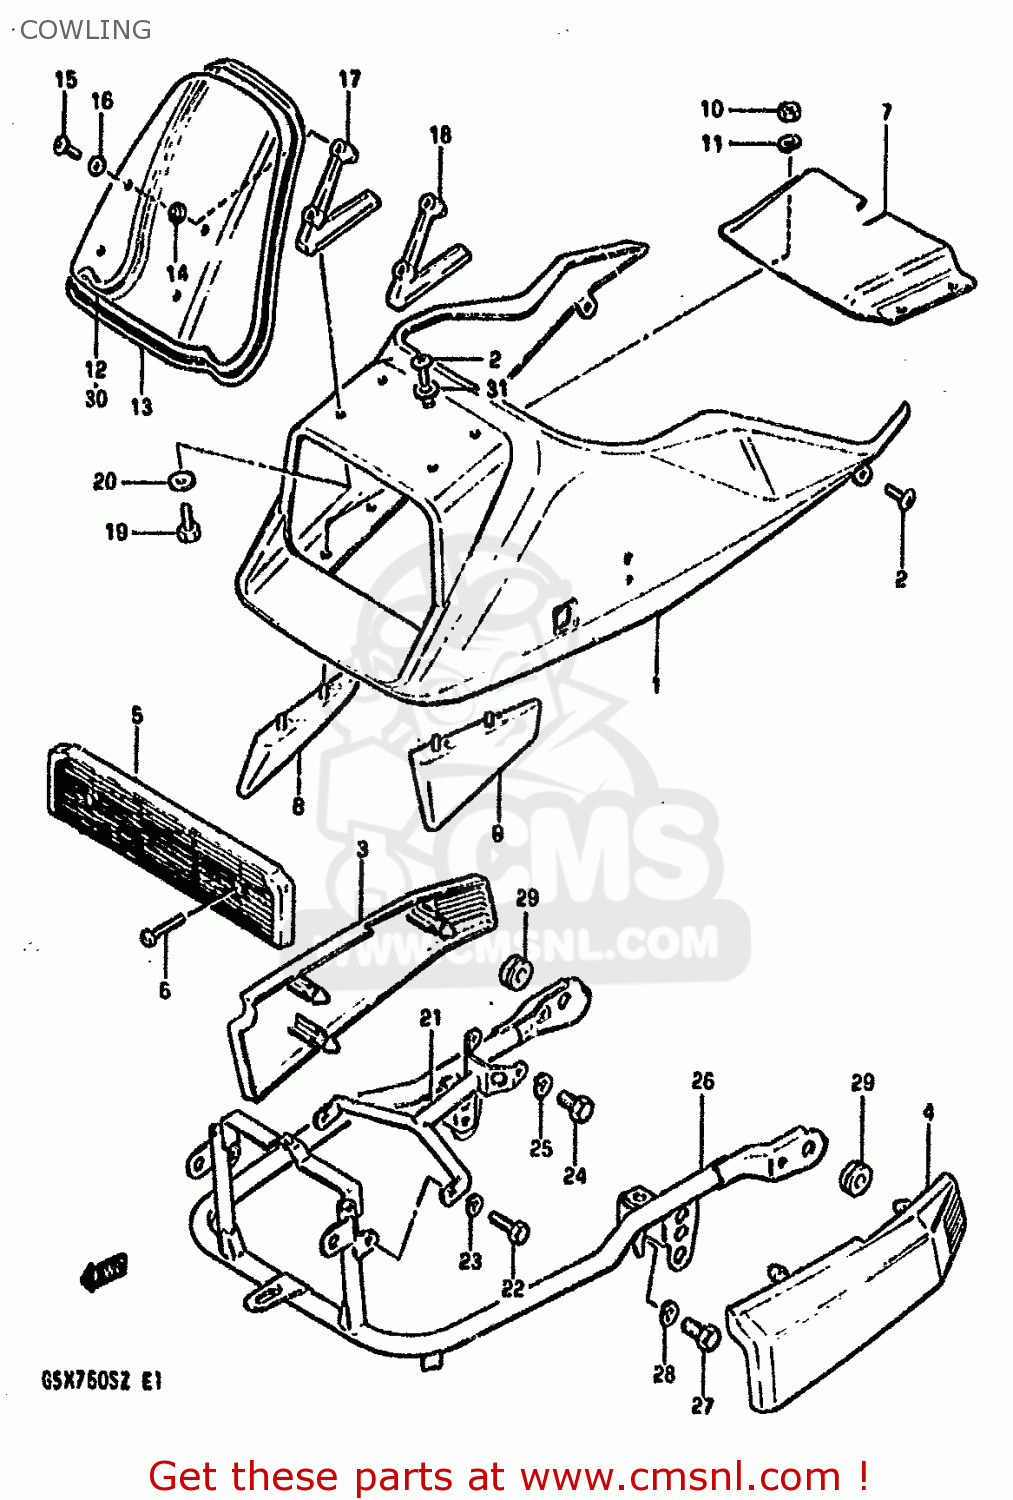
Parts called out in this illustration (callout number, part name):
1	BODY, COWLING (BLACK/RED)
2	SCREW 6X12
3	COVER, RH (RED)
4	COVER, LH (RED)
5	COVER,COWLING LOWER
6	SCREW 6X30
7	COVER,COWLING LOWER FR
8	WING,COWLING RH
9	WING,COWLING LH
10	NUT
11	LOCK WASHER
12	WINDOW,COWLING
13	MOLD,COWLING
14	CUSHION
15	SCREW
16	WASHER(5.2X11X1)
17	BRACE,COWLING WINDOW RH
18	BRACE,COWLING WINDOW LH
19	BOLT
20	WASHER(6.5X16X1.2)
21	BRACKET,COWLING UPPER
22	BOLT, UPPER
23	LOCK WASHER
24	BOLT 8X12
25	LOCK WASHER
26	BRACE,COWLING RR
27	BOLT 8X12
28	LOCK WASHER
29	CUSHION
30	WINDOW,COWLING
31	WASHER
